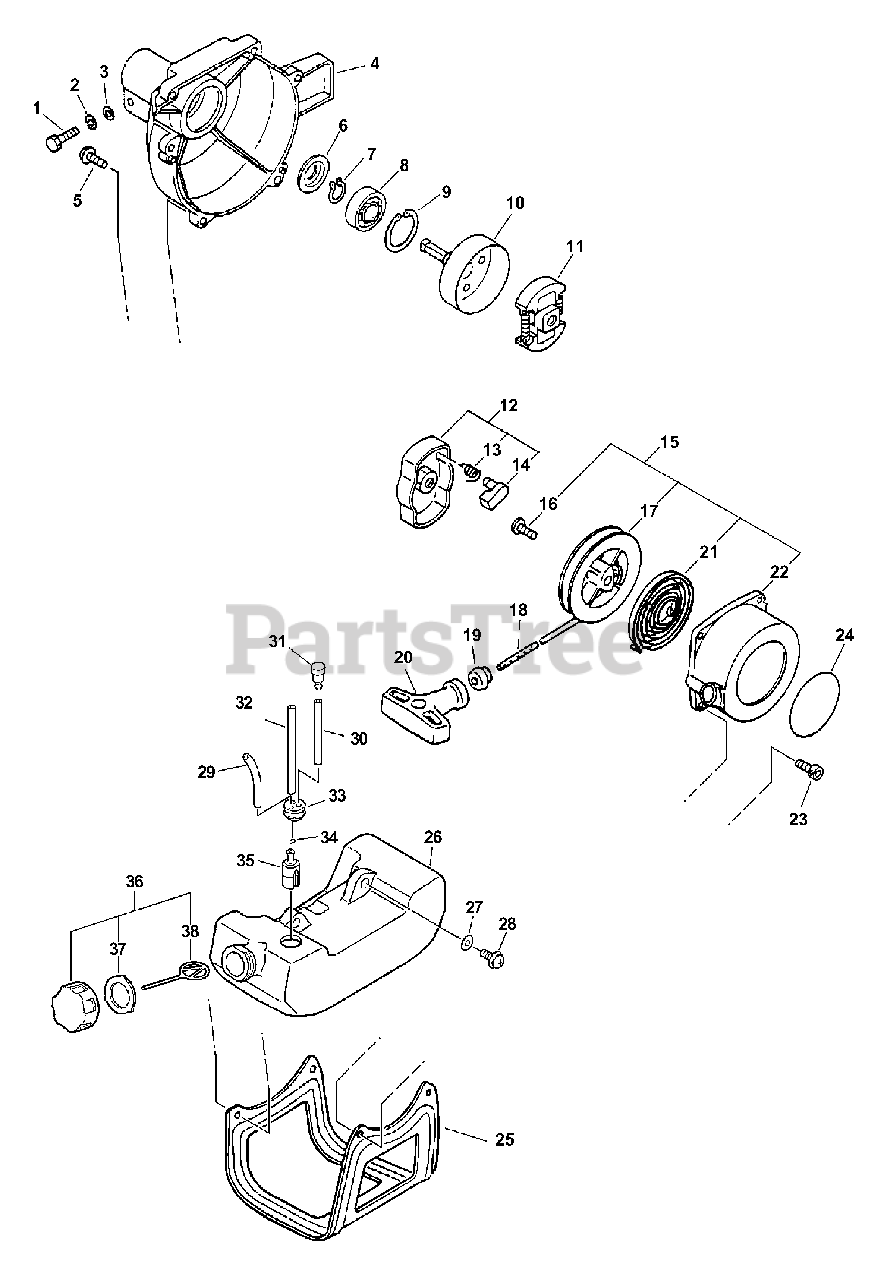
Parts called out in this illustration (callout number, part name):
1	BOLT - 5X25
2	LOCKWASHER - 5
3	WASHER - 5
4	CASE, FAN - ORANGE
5	SCREW - 4X16
6	RETAINER, PIPE
7	RING, RETAINING - 12
8	BEARING, BALL - 6201
9	RING, RETAINING - 32
10	DRUM, CLUTCH
11	CLUTCH ASSY
12	STARTER PAWL ASSY
13	SPRING, RETURN
14	PAWL, STARTER - BLACK
15	STARTER ASSY
17	REEL, ROPE
18	ROPE, STARTER - 3X1000
19	GUIDE, ROPE
20	GRIP, STARTER
21	SPRING, REWIND
22	CASE, STARTER
23	SCREW - 4X16
24	LABEL - ECHO
25	GUARD, FUEL TANK
26	FUEL TANK ASSY
27	WASHER - 5
28	SCREW - 5X16
29	PIPE - 3X6X90 -- CLEAR
30	PIPE - 3X5X70 -- BLACK
31	VENT, FUEL TANK
32	PIPE - 3X5X180 -- BLACK
33	GROMMET
34	CLIP - 6
35	FILTER, FUEL
36	CAP ASSY
37	GASKET, CAP
38	CONNECTOR, CAP
